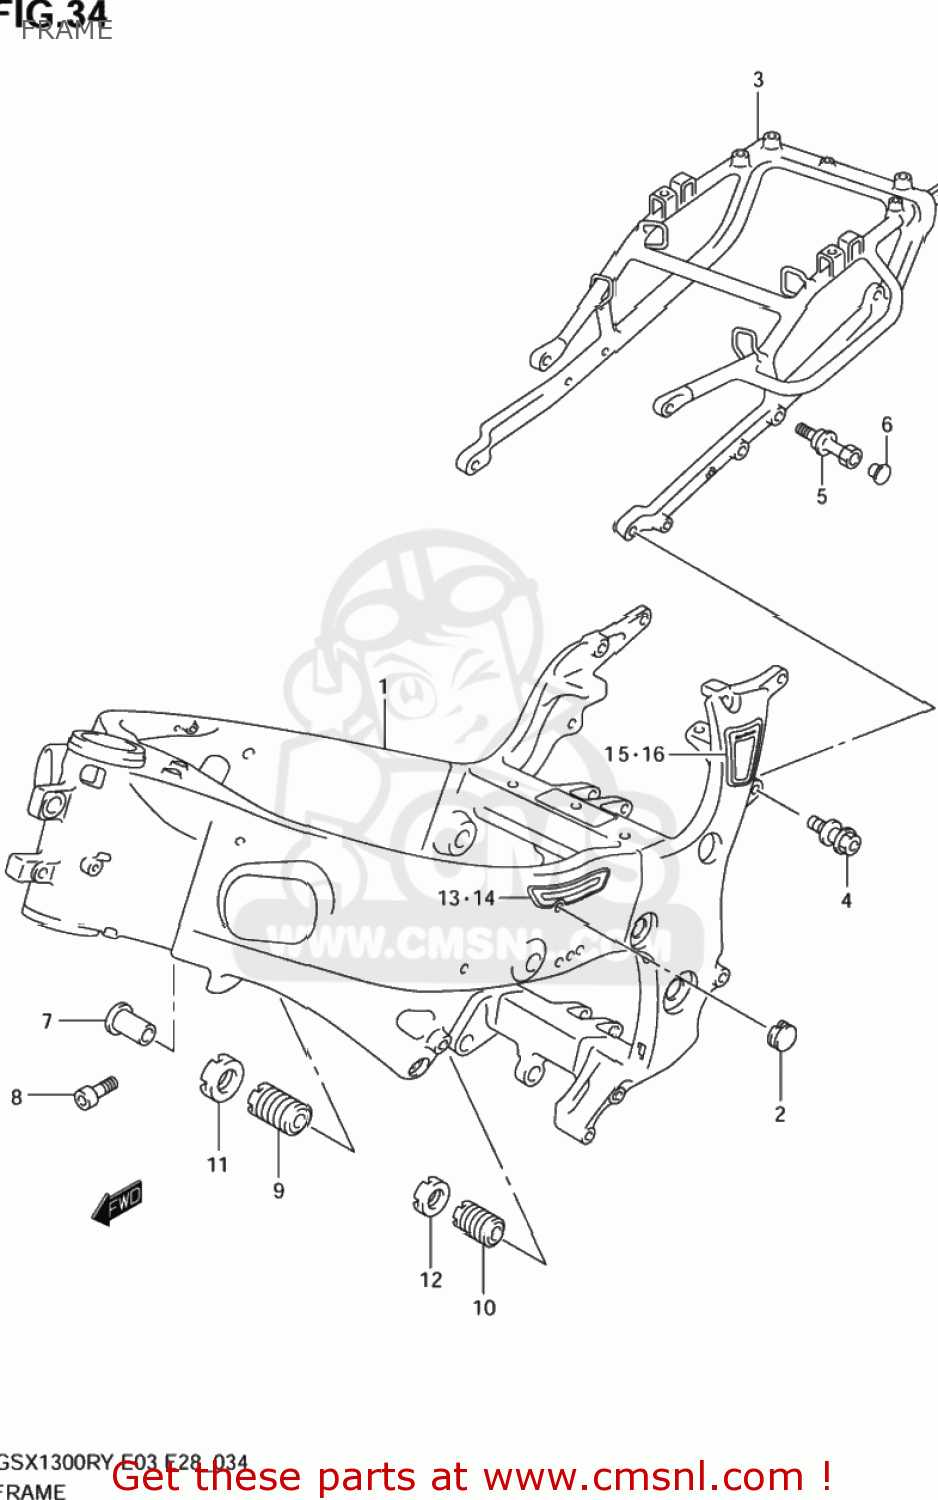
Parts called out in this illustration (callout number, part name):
1	FRAME
2	CAP,TANK RAIL
3	RAIL,SEAT
4	BOLT(10X30)
5	HOOK,SEAT RAIL
6	CAP(OD:10)
7	SPACER,ENGINE MTG
8	BOLT(8X30)
9	BOLT,CRANKCASE ADJUST
10	BOLT,CRANKCASE ADJUST
11	NUT,CRANKCASE ADJUST
12	NUT,CRANKCASE ADJUST
13	PAD,TANK RAIL,R
14	PAD,TANK RAIL,L
15	EMBLEM,FRAME BODY,R
16	EMBLEM,FRAME BODY,L
